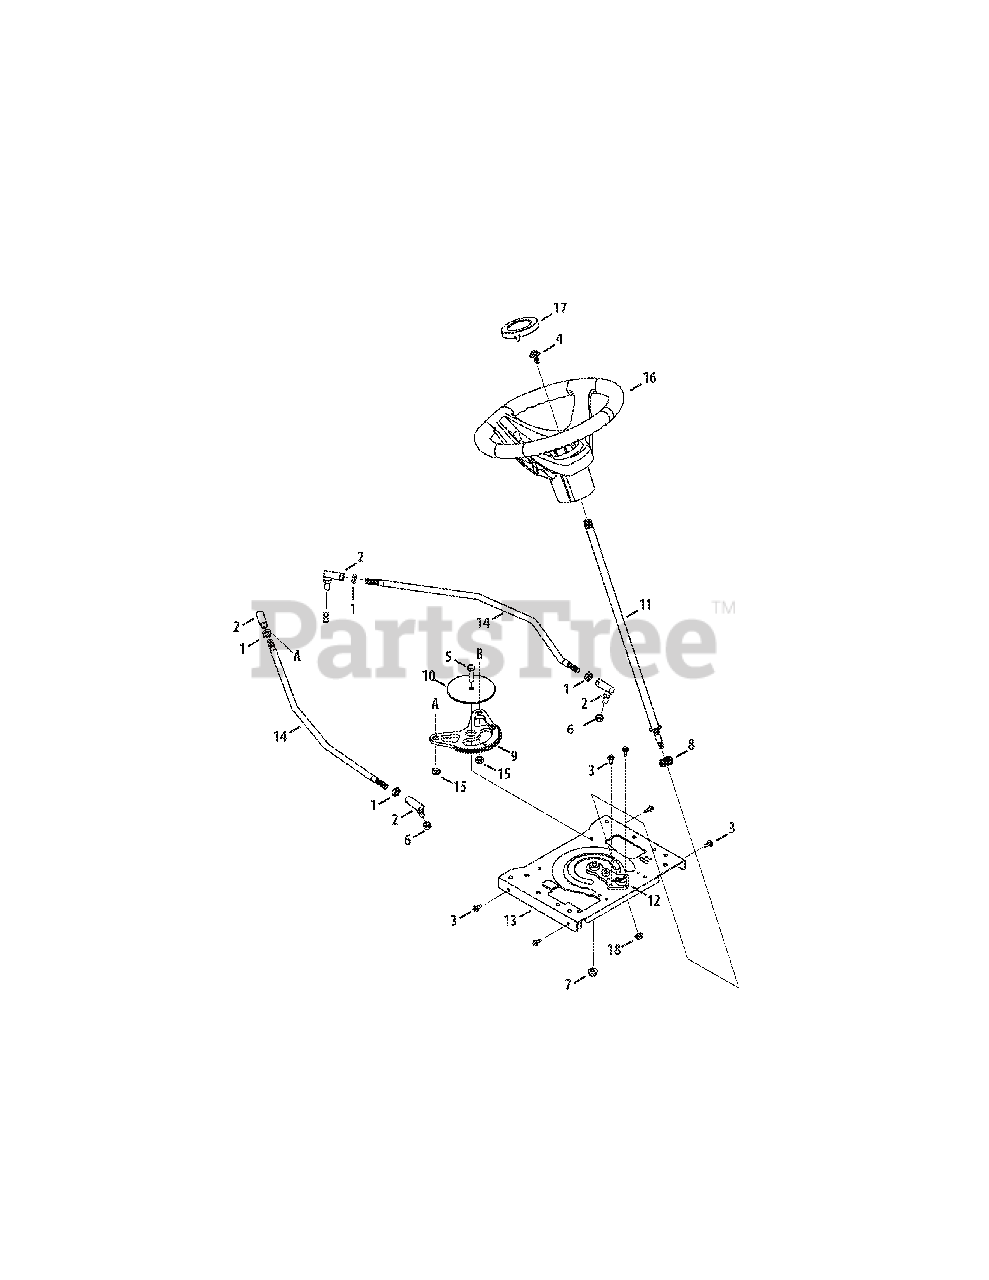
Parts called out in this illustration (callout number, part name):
1	Jam Nut, 1/2-20
2	Ball Joint, 1/2-20, Lock
3	Screw, M6-1 x .625
4	Screw, 5/16-24 x .850
5	Hex Cap Screw, 3/8-16 x 1.25
6	Nut, Hex Lock, 7/16-20
7	Nut, Flange Lock, 3/8-16, Grf,
8	Pinion Gear, 13T
9	Steering Gear
10	Flat Washer, .385 x 4.0 x .120
11	Shaft, Steering, .625 OD x 20
12	Steering Support
13	Steering Mounting Plate
14	Steering Rod Assy (Incl. ref. 1 & 2)
15	Jam Nut, 7/16-20
16	Steering Wheel
17	Cap, Steering Wheel
18	Nut, Flange Lock, 5/16-18, Grf
